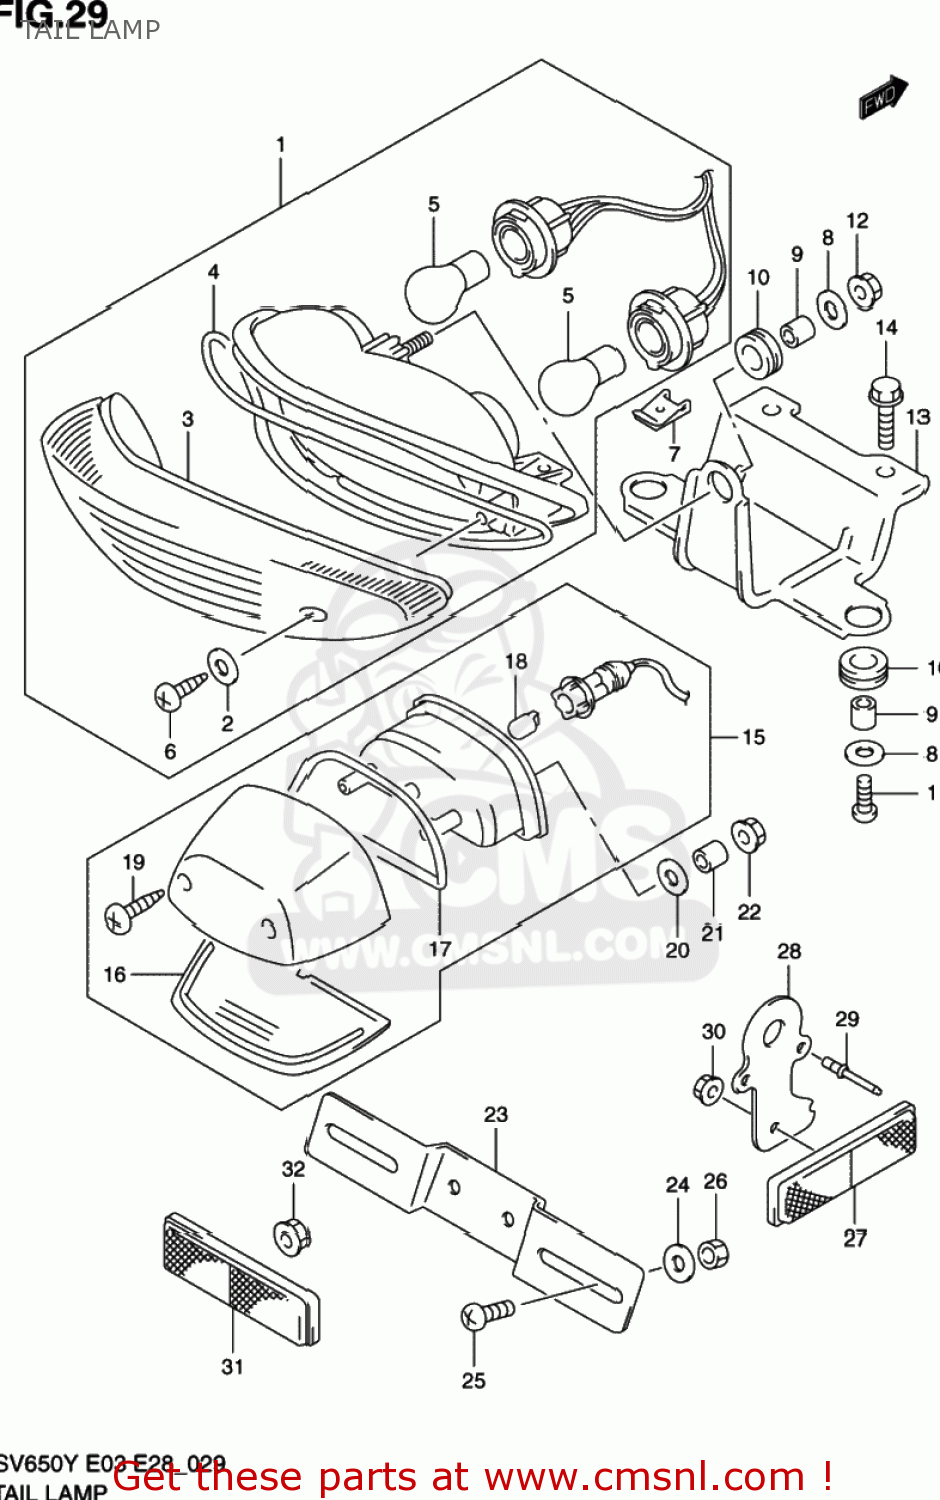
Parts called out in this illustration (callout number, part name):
1	LAMP ASSY,RR COMBINATION
2	GASKET (NAS)
3	LENS
4	GASKET (NAS)
5	BULB(12V21/5W,BF141-49642A)
6	SCREW
7	NUT
8	WASHER(6.5X20X1.6)
9	SPACER(6.5X10X9)
10	CUSHION
11	SCREW
12	NUT
13	BRACKET,RR COMBINATION LAMP
14	BOLT
15	LAMP ASSY,LICENSE
16	LENS
17	GASKET (NAS)
18	BULB(12V5W)
19	SCREW
20	WASHER(6.5X20X1.6)
21	SPACER(5.5X9.5X11.5)
22	NUT
23	BRACKET,LICENSE PLATE
24	WASHER(6.5X20X1.6)
25	SCREW 6X12
26	NUT
27	REFLECTOR ASSEMBLY,REAR
28	BRACKET,RR SIDE RR
29	RIVET
30	NUT
31	REFLECTOR ASSEMBLY,REAR
32	NUT
